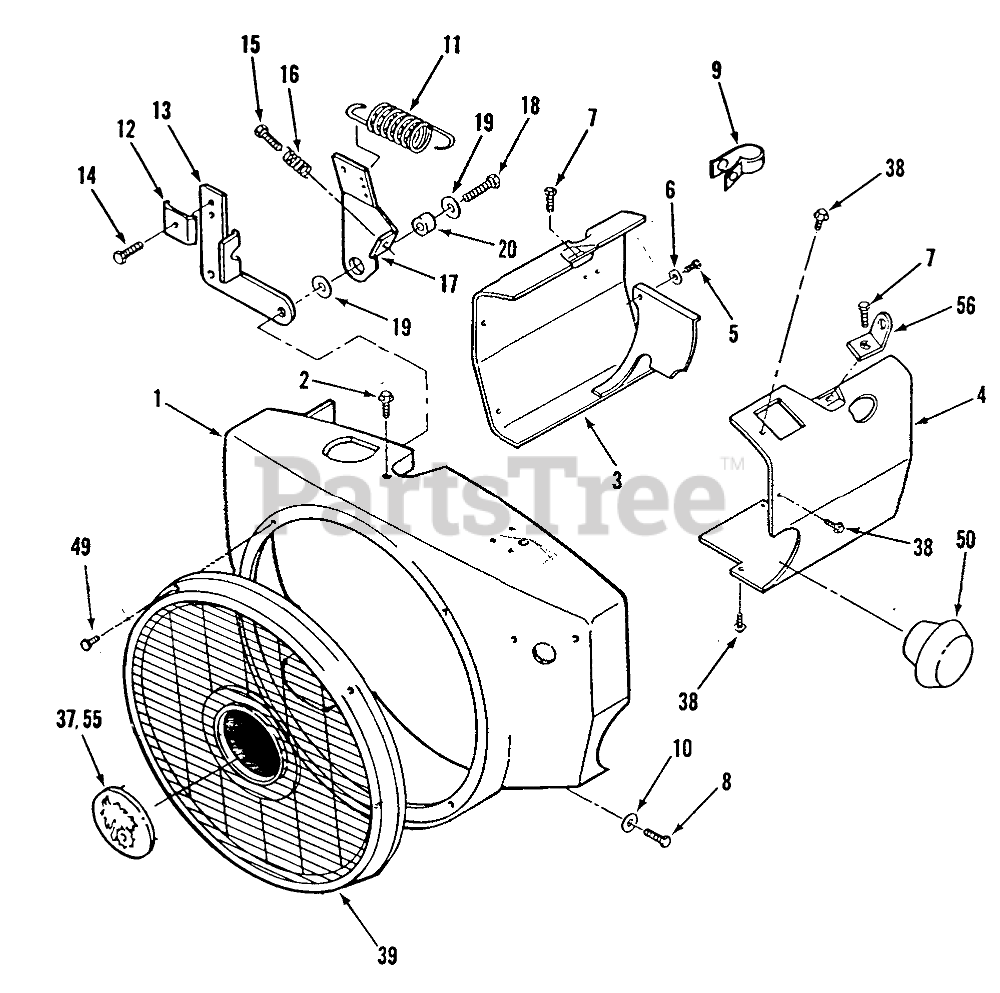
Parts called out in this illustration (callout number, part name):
1	Blower Housing
2	Screw, Cap-Hex. Hd.
3	Cylinder Air Housing
4	Cylinder Air Housing
5	Screw, Cap-Hex Hd.
6	Washer, Flat
7	Wash. Hd. Screw 5/16-18 x 3/4
8	Screw, Cap-Hex Hd.
9	Camp, Wire-Alternator Leads
10	Washer, Flat
11	Spring, Governor
12	Cable Clamp
13	Bracket Cable
14	ST Screw nr. 10-32 x 1/2
15	Screw, Tapping Hex Head
16	Spring Idle Setting
17	Arm-Governor Control
18	Screw-Cap Hex Washer Hd.
19	Washer, Flat
20	Bushing Control Arm
37	Black Nylon Bushing
38	Screw, Cup Hex Washer Hd.
39	Stationary Guard
49	Wash. Hd. Screw 1/4-20 x 3/8
50	Hole Plug
55	Nameplate Logo
56	Lifting Bracket
